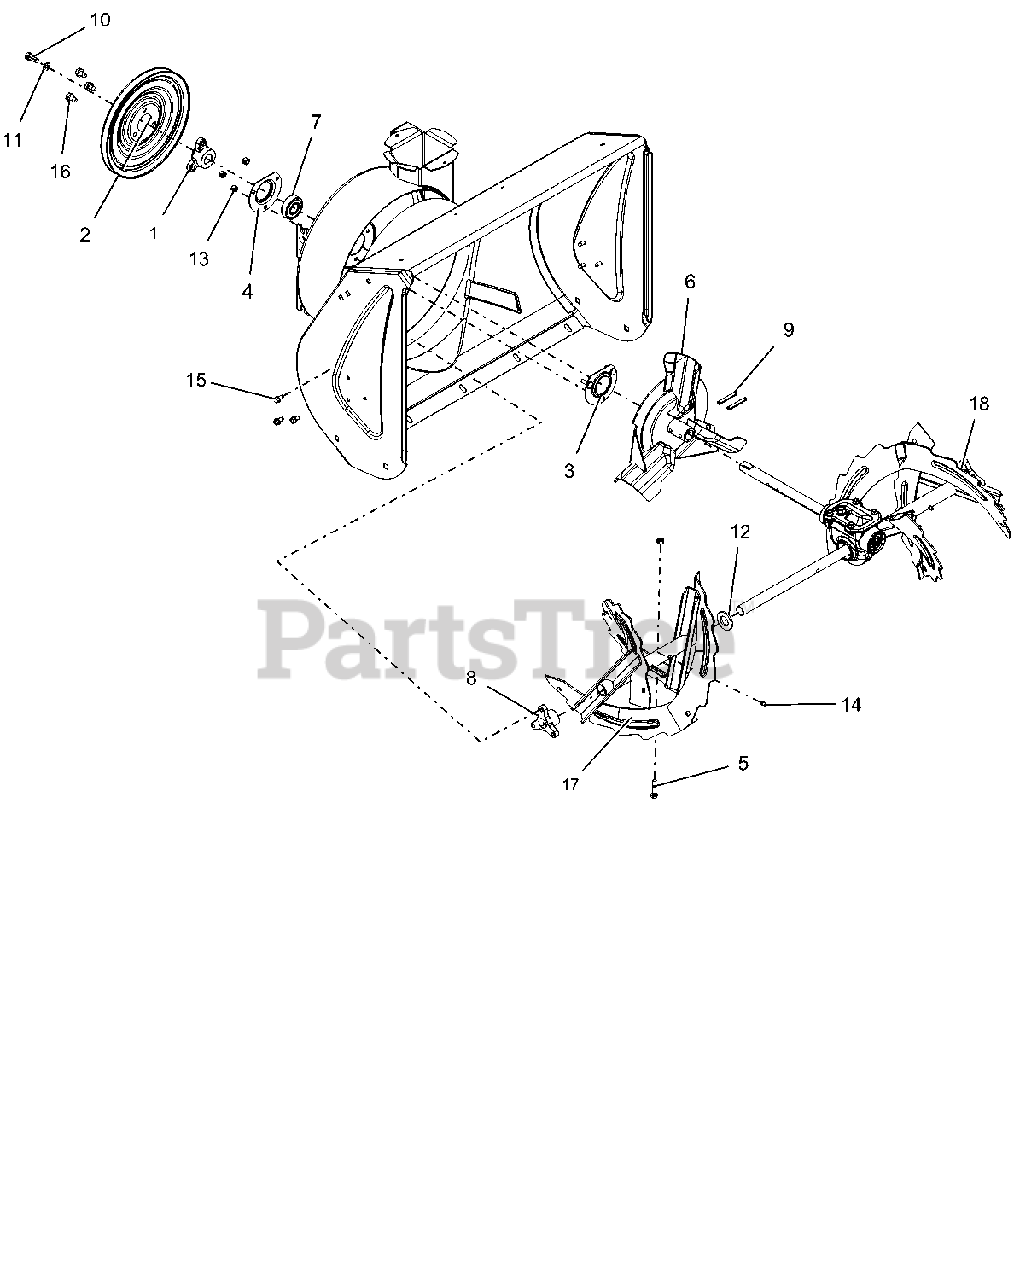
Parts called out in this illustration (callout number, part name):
1	PULLEY HUB, BOLT-ON D-BORE .75
2	PULLEY,SPIN FORM SINGLE GROOVE
3	BEARING FLANGE
4	BEARING FLANGE
5	SHEAR BOLT WITH NUT
6	IMPELLER, COMPACT 12" 3-BLADE
7	BRG-BALL .750X1.750X.50
8	BUSHING, RAKE SHAFT .75"
9	PIN-ROLL .250X1.75
10	BLT-HEX .31-24X.75 YWZC GR5
11	WSHR-LK .312X.097 HVY YWZC
12	@WSHR-FL-STL.812X1.50X.135YWZC
13	@NUT-LK-CTR .25-20 YWZC
14	ZERK,FITTING .25X.125 DRIVE IN
15	SCR-TAP .25-20X.50 HWH TR YWZ
16	@SCR-TAP .31-18X.50 HWH TR YWZ
17	RAKE, 24" RH, BLK SERR W/ZERK
18	RAKE, 24" LH, BLK SERR W/ZERK
